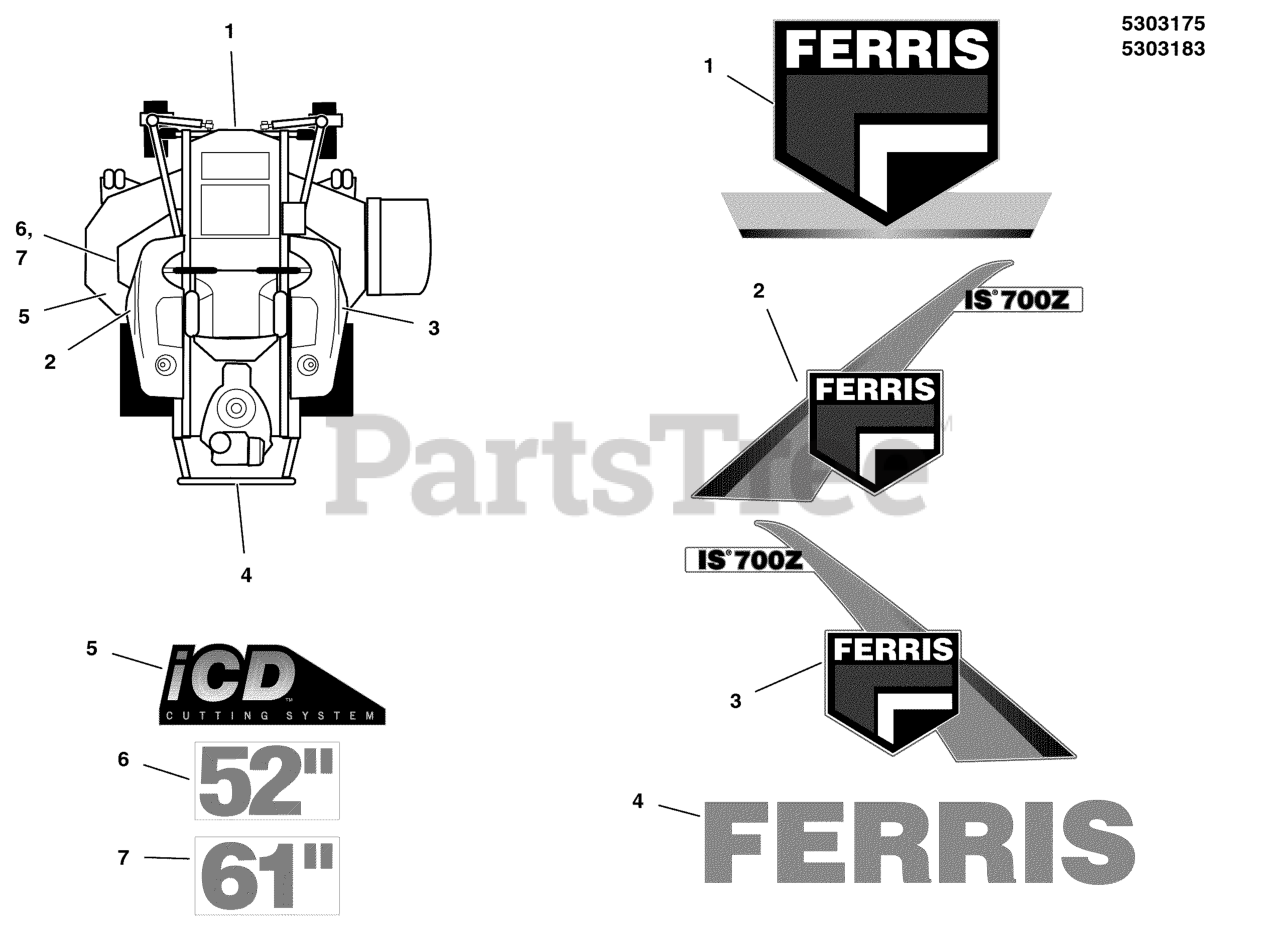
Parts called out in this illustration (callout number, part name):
1	DECAL, FERRIS, FRONT, 8.78 X 5.81
2	DECAL, BADGE, LH IS700
3	DECAL, BADGE, RH IS700
4	DECAL, FERRIS, 2.23" X 11.39"
5	DECAL, iCD CUTTING SYSTEM
6	DECAL, 52
7	DECAL, 61
